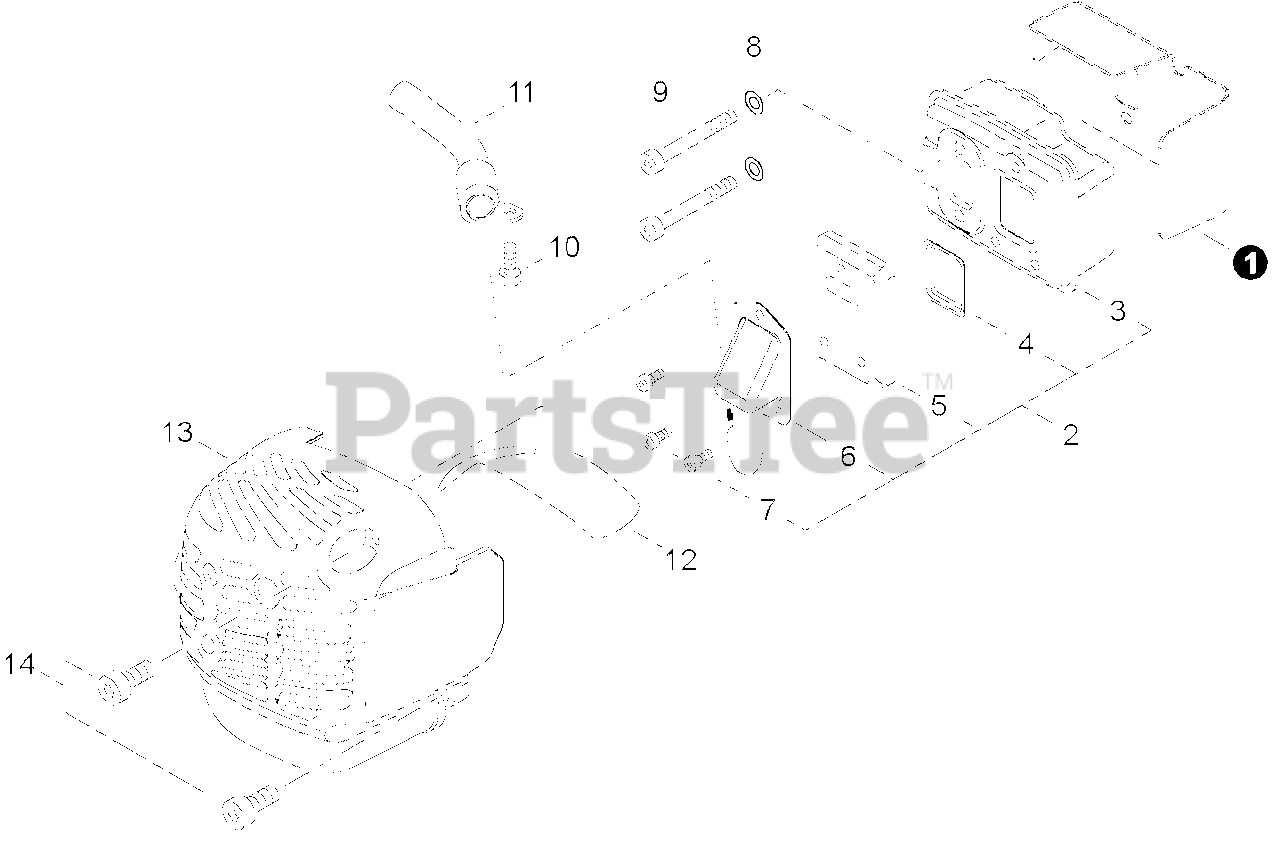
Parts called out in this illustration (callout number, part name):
1	HEAT SHIELD, EXHAUST
2	MUFFLER ASSY
3	MUFFLER
4	SCREEN, SPARK ARRESTER
5	GASKET, EXHAUST
6	GUIDE, EXHAUST
7	BOLT, TORX 4×8
8	WASHER 5.5×12×0.8
9	BOLT, TORX 5×55
10	BOLT, TORX 5×10
11	GUIDE, EXHAUST
12	PLATE, INSULATOR
13	COVER, MUFFLER
14	BOLT, TORX 5×16
